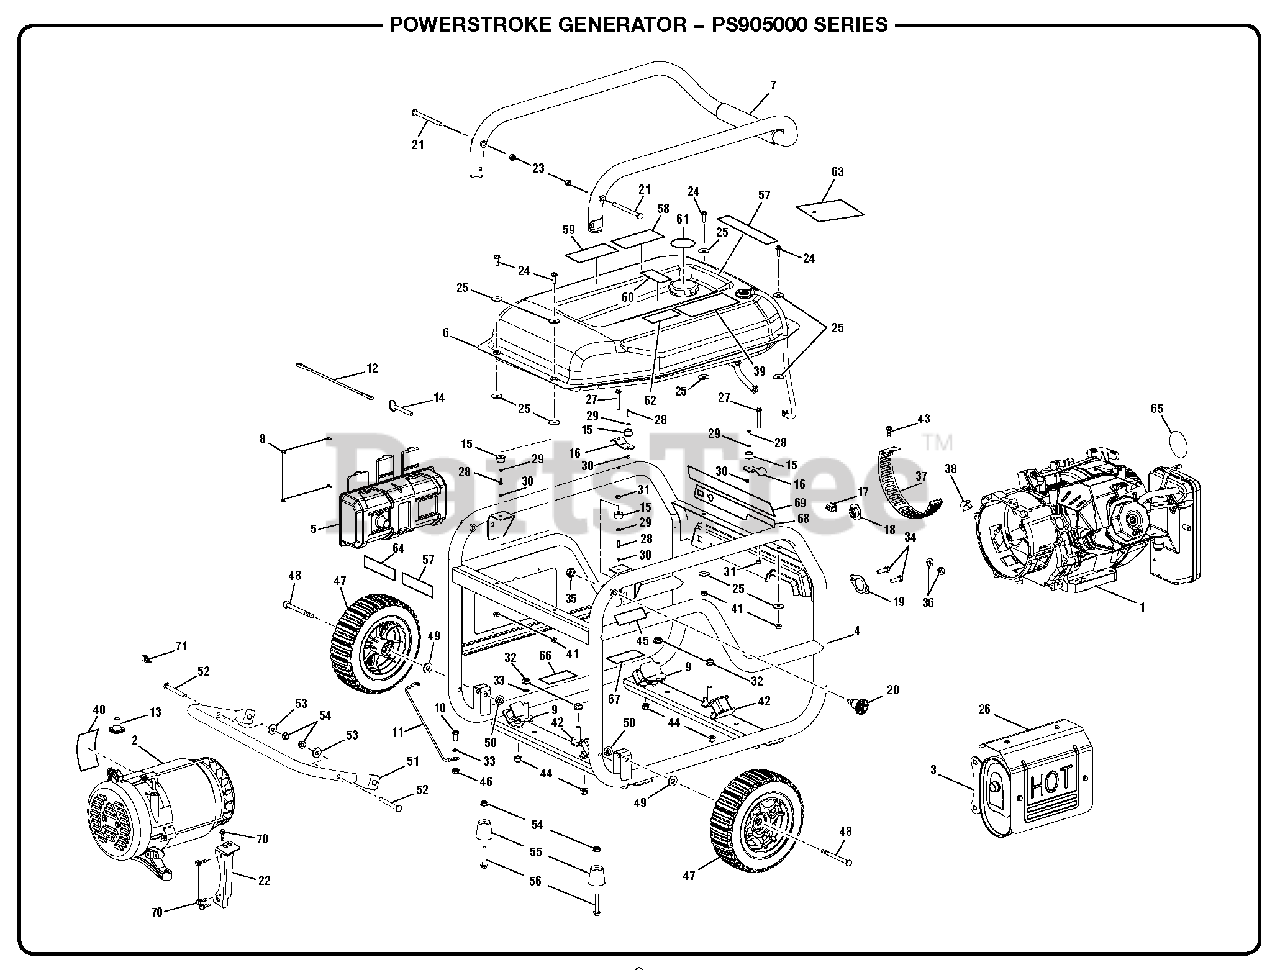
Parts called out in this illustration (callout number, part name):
1	Engine (390cc)
2	Generator Head Assembly (See Fig. A)
4	Frame Assembly
5	Control Panel Assembly (See Fig. C)
6	Fuel Tank Assembly (See Fig. B)
7	Handle Assembly
8	Screw (6-20 x 3/8 in.)
9	Engine Isolator (Right)
10	Bolt (5/16-18 x 3/4 in.)
11	Ground Wire Assembly
13	Rubber Sleeve
14	Release Pin
15	Handle Bumper
16	Handle Support Bracket
17	On/Off Switch
18	Fuel Valve Bezel
19	Muffler Gasket
20	Handle Release Pin
21	Pivot Pin (Handle)
22	Muffler Bracket
23	Lock Nut (5/16-18)
24	Bolt (M6 x 20 mm, Hex Washer Hd.)
25	Washer (M6)
26	Heat Shield
27	Bolt (M6 x 45 mm)
28	Bolt (M4 x 12.5 mm, Hex Hd.)
29	Washer (M4)
30	Lock Nut (M4)
31	Lock Nut (M6)
32	Lock Nut (5/16-18)
33	Star Washer (5/16 in.)
34	Bolt (M8 x 25 mm, Hex Hd.)
35	Lock Nut (1/2-20)
36	Hex Nut (M8)
37	Fan Cover (Generator Head)
38	Plug (Generator Head)
39	Danger Label
40	Data Label
41	Flange Nut (M6)
42	Engine Isolator (Left)
43	Bolt (M6 x 14 mm)
44	Lock Nut (M8)
45	Hot Surface Label
46	Hex Nut (5/16-18)
48	Bolt (M10 x 1-1/4 in.)
49	Washer (M10)
50	Lock Nut (M10)
51	Foot Rest
52	Bolt (M8 x 1-1/4 in.)
53	Washer (M8)
54	Lock Nut (M8)
55	Foot Assembly
56	Bolt (M8 x 1-1/4)
57	Fire Distance Label (Eng/Sp)
58	CPSC Label
59	Fire Danger Label
60	E85 Label
61	Fuel Stabilizer Label
62	Combustion Label (Eng/Sp)
63	Warning Hangtag
64	Ground Warning Label
65	Recoil Housing Label
66	Lubricant Label
67	Inquires label
68	Start Label
69	Logo Label
70	Bolt (M8 x 1.25, Hex Hd.)
71	Ground Lug (5/16-24)
